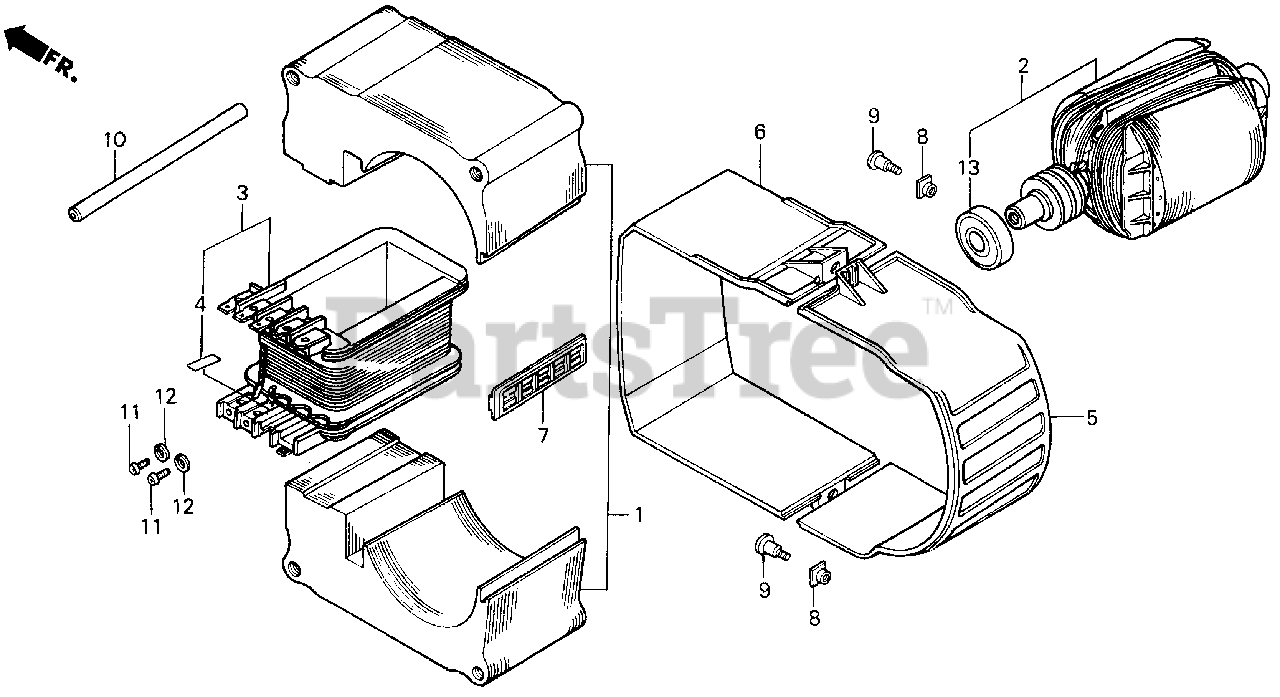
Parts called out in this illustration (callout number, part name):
1	CORE SET, STATOR
2	ROTOR (EZ-R)
3	BOBBIN, STATOR COIL
4	MARK, WIRE COLOR
5	COVER, R. STATOR (NOT AVAILABLE)
6	COVER, L. STATOR
7	STIFFENER, STATOR (NOT AVAILABLE)
8	NUT, SPECIAL (5MM)
9	BOLT, STATOR COVER SETTING
10	PIN, DOWEL (11X121)
11	SCREW, PAN (5X8)
12	WASHER, SPRING (5MM)
13	BEARING ASSY. (6203)
13	BEARING, RADIAL BALL (6203UU)
